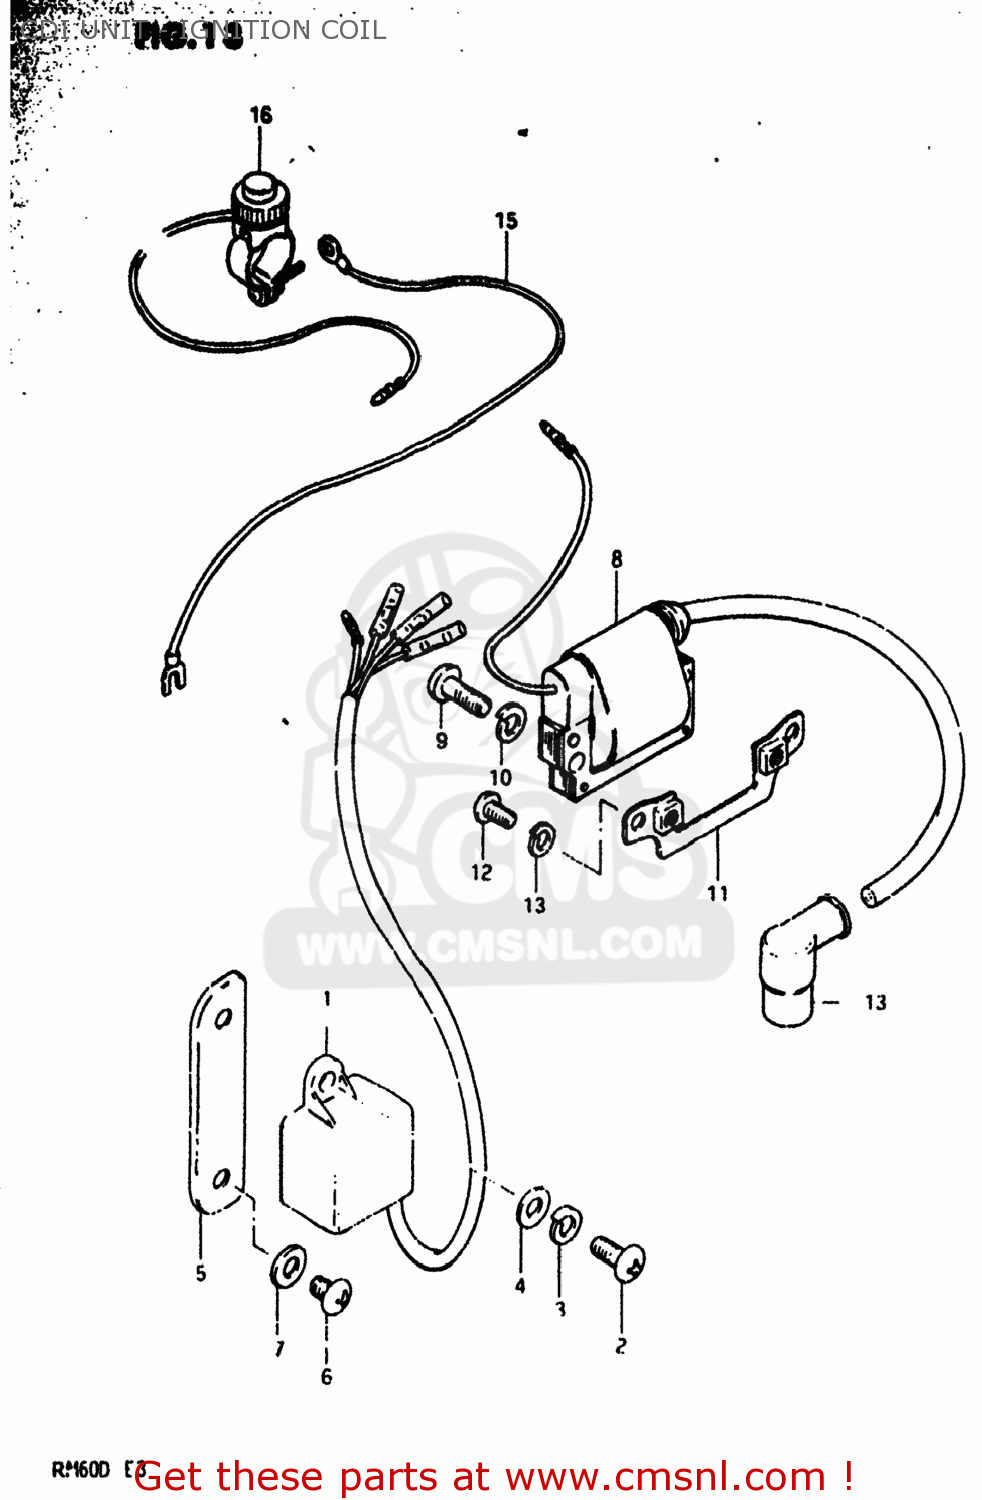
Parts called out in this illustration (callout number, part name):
1	CDI UNIT ASSEMBLY
2	SCREW
3	LOCK WASHER
4	WASHER
5	BRACKET,IGNITER
6	SCREW
7	WASHER
8	COIL ASSEMBLY,IGNITION
9	SCREW
10	LOCK WASHER
11	BRACKET,IGNITION COIL
12	SCREW
13	LOCK WASHER
14	CAP,SPARK PLUG
15	WIRE,ENGINE STOP EARTH
16	SWITCH ASSEMBLY
